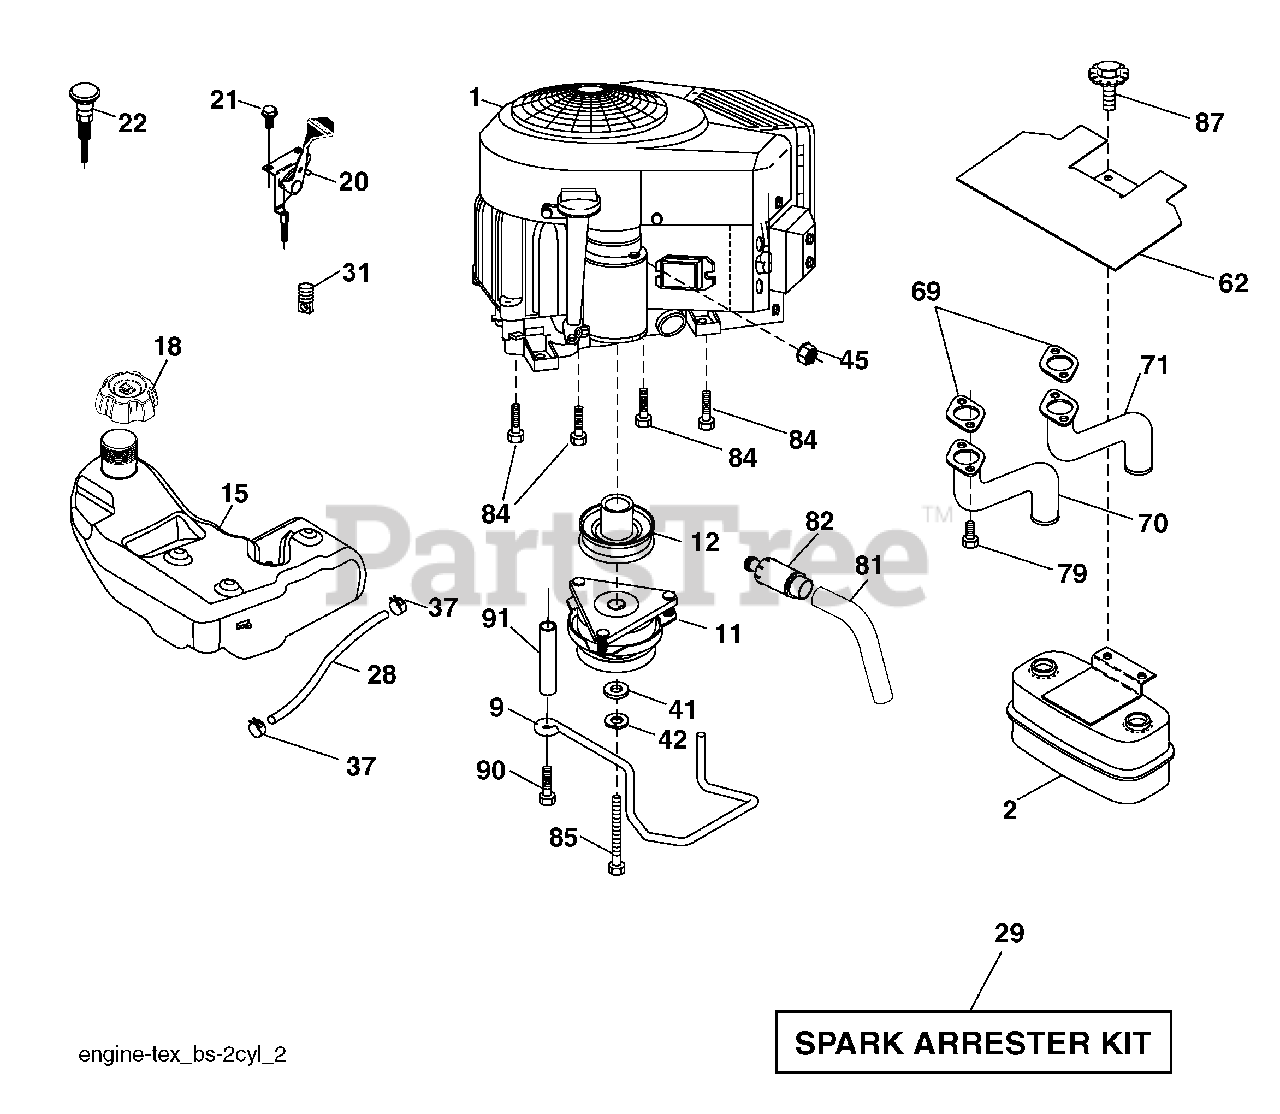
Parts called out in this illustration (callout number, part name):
2	Muffler
9	Keeper Belt Engine
11	Clutch Electric
12	Pulley Engine
15	Tank Fuel
18	Cap Asm.
20	Control Throttle
21	Screw #10 x 0.750 BOS Thread
22	Control Choke
28	Fuel Line
29	Spark Arrester Kit
31	Clip Push-In Hinged
37	Clamp Hose
41	Washer 1-1/2 OD x 15/32 ID x .250
42	Washer Lock 7/16
45	Nut Keps Hex 1/4-20 unc
62	Shield Heat Muffler
69	Gasket
70	Exhaust Tube LH
71	Exhaust Tube RH
79	Screw Socket Head 5/16-18 x 1
81	Tube Drain Oil Easy
82	Plug Drain Oil
84	Screw 3/8-16 x 1-1/4
85	Bolt Hex 7/16-20 x 3.75 Gr. 5
87	Bolt 5/16-18 x 1
90	Screw 3/8-16 x 1
91	Bushing 1.375 OD
